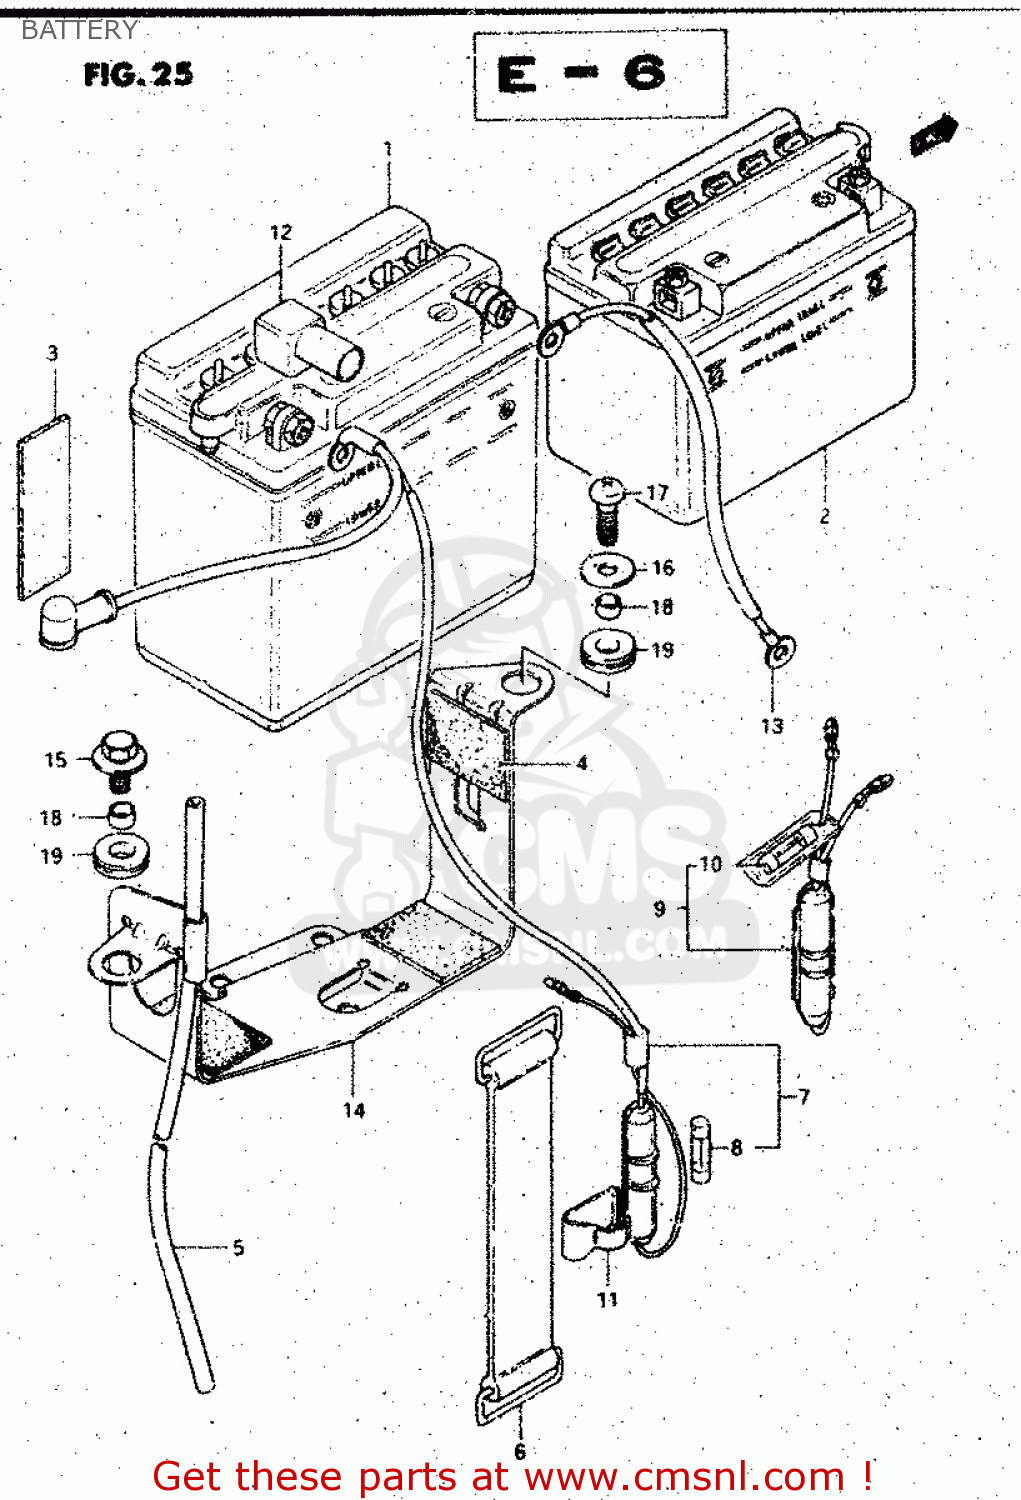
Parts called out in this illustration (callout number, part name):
1	BATTERY ASSY(YB7-A)
2	BATTERY ASSY(YB4L-B,12V4.2AH)
3	PROTECTOR(170X95X3.0)
4	PROTECTOR(170X95X3.0)
5	HOSE,BATTERY EXHAUST(L:780)
6	BAND
7	FUSE CASE AND PLUS CABLE
8	FUSE(15A)
9	CASE ASSY,FUSE
10	FUSE(10A)
11	HOLDER,FUSE CASE
12	CAP,TERMINAL
13	LEAD WIRE,BATTERY(-)
14	HOLDER,BATTERY
15	BOLT 6X16
16	WASHER (6.5X20X1.2)
17	SCREW(6X21)
18	SPACER(6.1X9X7.5)
19	CUSHION
